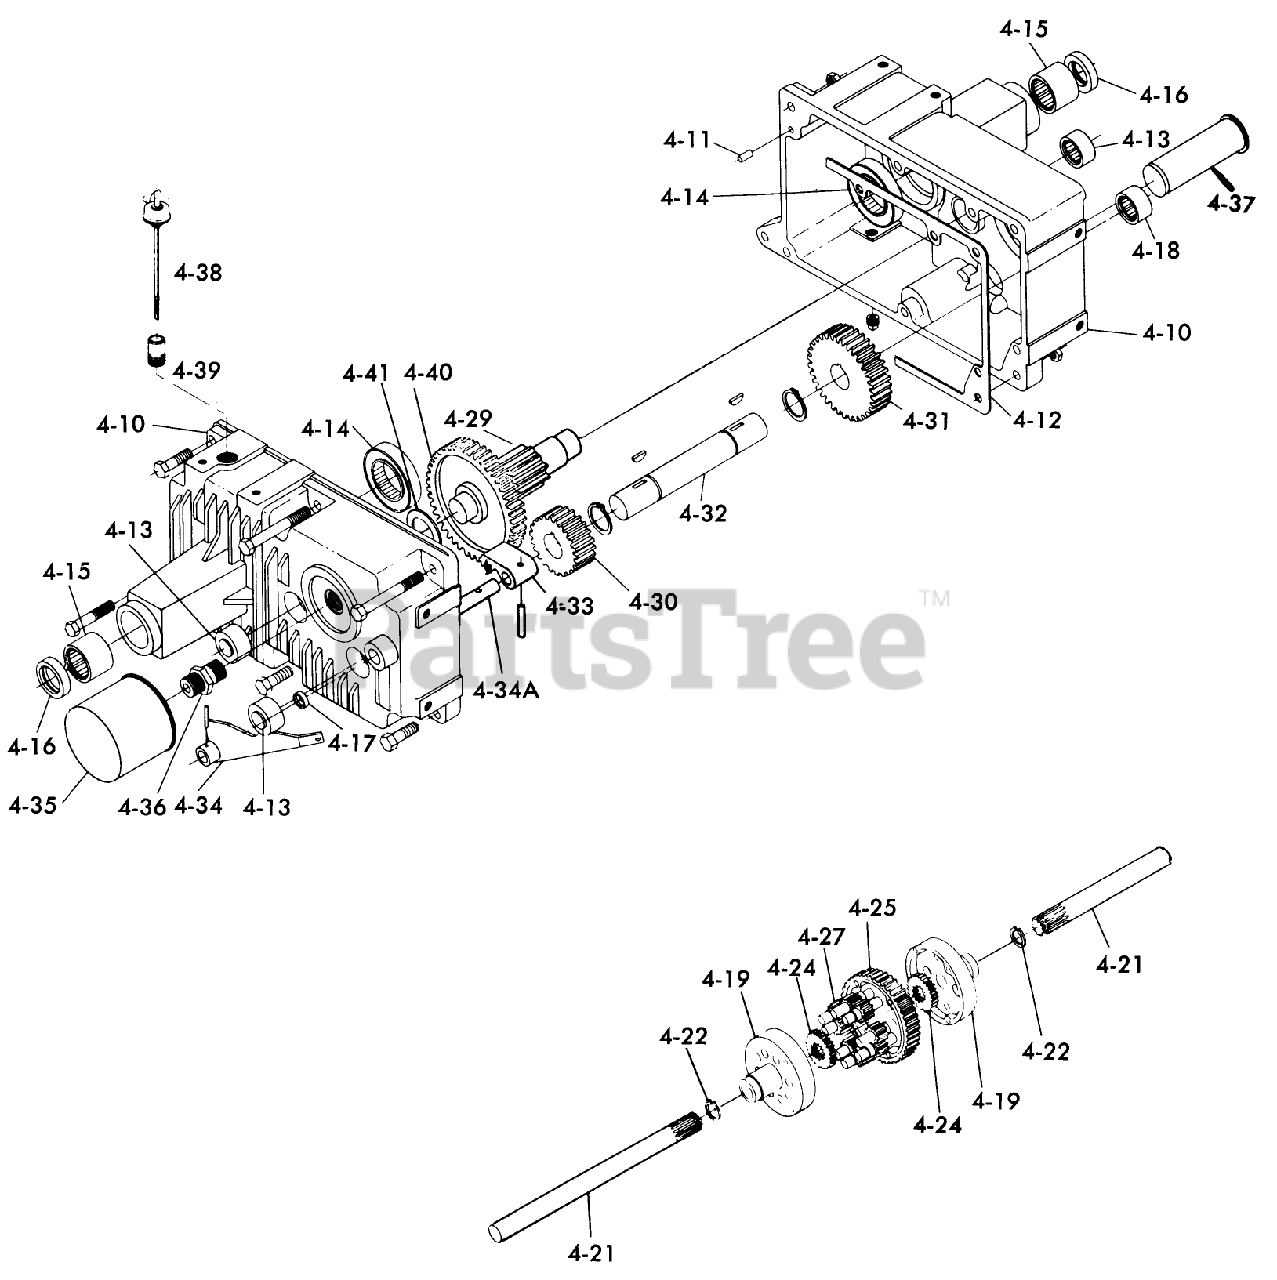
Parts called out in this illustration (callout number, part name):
4-10	RH TRANSMISSION CASE
4-10	Case LH
4-10	PLUG 1/4 PIPE ALLEN
4-10	H H C S
4-10	HHCS
4-10	Bolt
4-10	Washer
4-10	Nut
4-10	BOLT
4-11	PIN-DOWEL
4-12	GASKET
4-13	BEARING-NEEDLE
4-14	BALL BRG 1 1/2 I.D.
4-15	Bearing-Axle
4-16	SEAL-OIL
4-17	SEAL BRAKE SHAFT
4-18	Needle Bearing
4-19	End Cap
4-19	HHCS 5/16-18 X 3-1/2
4-19	Nut
4-21	Axle
4-22	SNAP RING
4-24	GEAR-AXLE DIFFERENTIAL
4-25	Gear-Bull
4-27	GEAR-PINION, 11T
4-30	GEAR 24T
4-31	Gear 44T
4-32	SHAFT GEAR
4-32	Snap Ring
4-32	Key
4-33	PAWL PARKING
4-34	Brake Lever
4-34A	Shaft
4-34A	Pin-Roll
4-34A	PIN-ROLL
4-35	Filter
4-36	FITTING
4-37	Strainer
4-38	Dipstick
4-39	Nipple
4-40	GEAR ASSY
4-40	PINION SHAFT
4-40	Gear-42T
4-41	WASHER-THRUST
